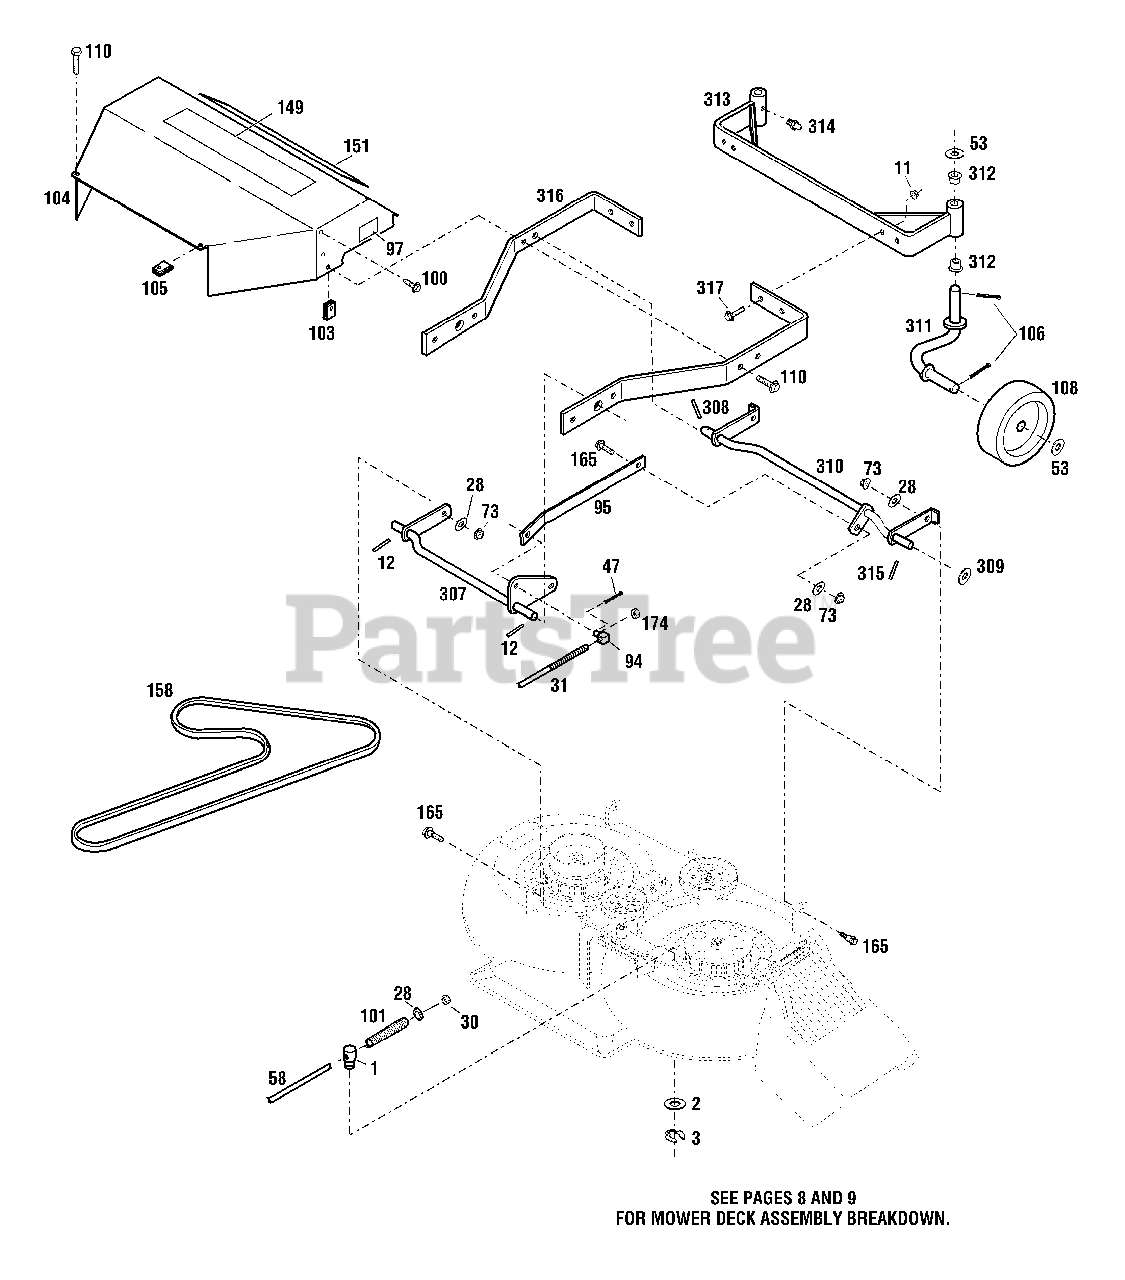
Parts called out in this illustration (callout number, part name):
3	Clip Ring
11	Flange Locknut, 3/8-16
28	Flat Washer, 3/8
30	Locknut, 3/8-16
31	Lift Crank
47	Cotter Pin
53	Special Washer
58	Lower Blade Rod
73	Flange Locknut, 3/8-16
94	Pivot Block
95	Leveler Bar
97	Cutting Height Decal
100	Tap Screw, #8 x 3/8
101	Compression Spring
103	Speed Nut, 5/16-18
104	Belt Guard
105	Speed Nut, 5/16-18
106	Cotter Pin
108	Gage Wheel
110	Flange Lock Screw, 5/16 x 3/4
149	Logo Decal
151	33" Combination Deck Decal
165	Shoulder Bolt
174	Toplock Nut
307	Rear Lift Assembly
308	Roll Pin, 1/4 x 1
309	Flat Washer, 5/8
310	Front Lift Assembly
311	Spindle Assembly
312	Flange Bearing
313	Gage Support
314	Grease Fitting
315	Drive Pin, 1/4 x 3
316	Mower Support
317	Whizlock Screw, 3/8-16 x 1
